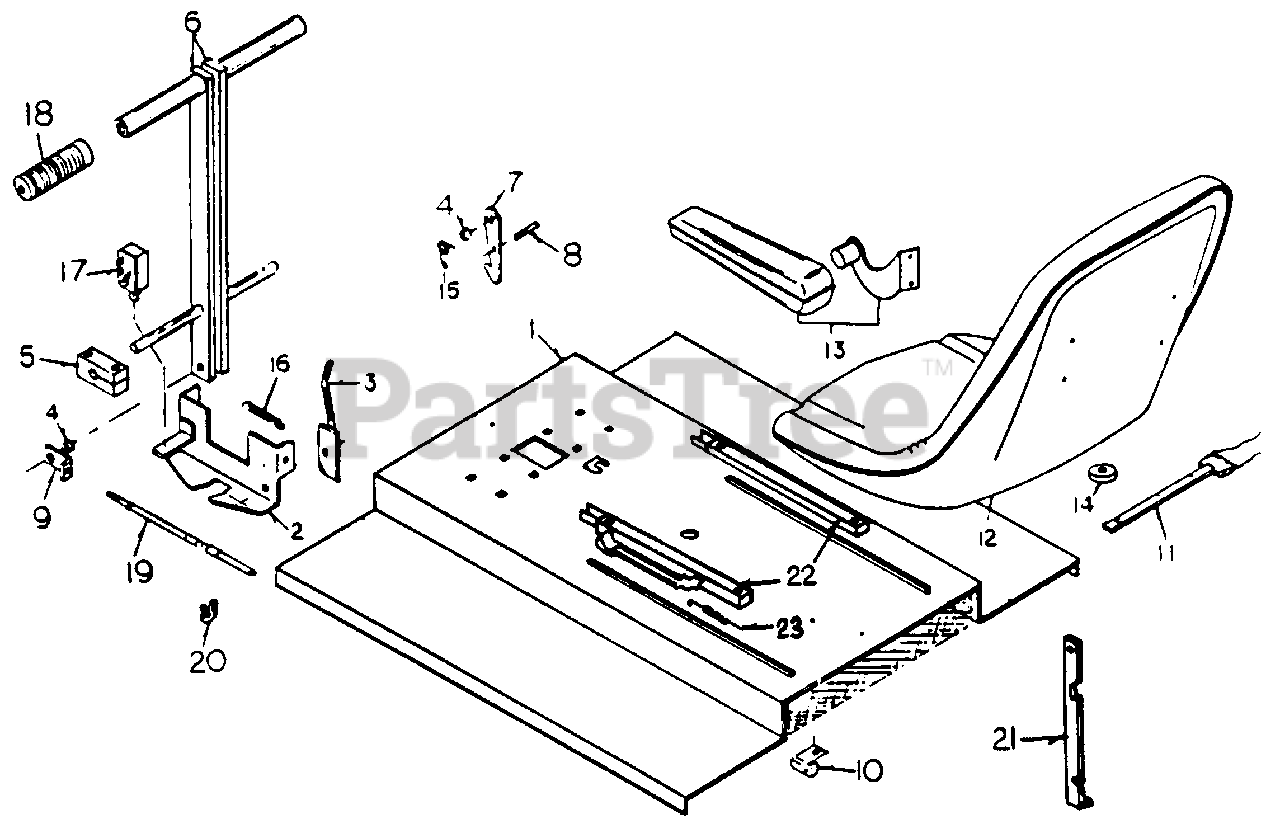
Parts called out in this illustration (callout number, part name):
3	Lacch, Lever Lock
4	Bushing
6	Steering Lever
7	Seat Lid Laech
8	Seat Lid Latch Bolt
9	Steering Cable End
10	Seat Lid Harness Retainer
13	(Optional)
15	Seat Lid Latch Spring
16	Lever Lock Spring
18	Handle Grip
19	Steering Cable
20	Steering Cable Clamp
22	Seat Rail Kit
